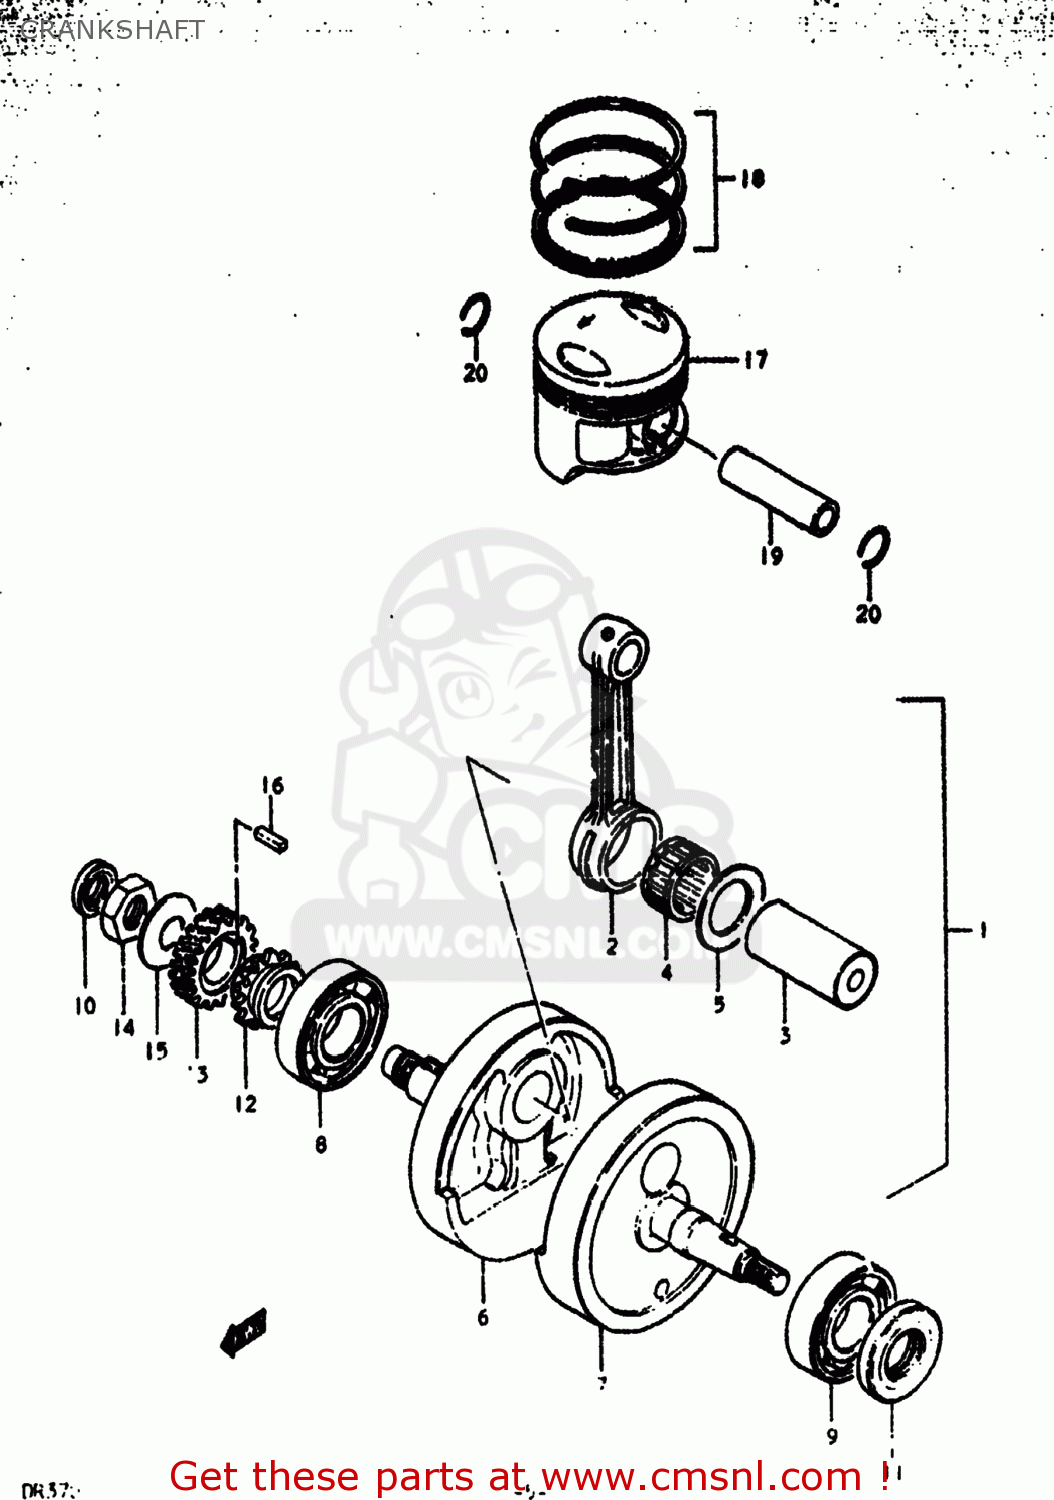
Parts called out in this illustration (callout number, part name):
1	CRANKSHAFT ASSEMBLY
2	ROD,CONNECTING
3	PIN,CRANK
4	BEARING
5	WASHER (32X50X1)
6	CRANKSHAFT
7	CRANKSHAFT,LEFT
8	BALL BEARING 30X72X19
9	BEARING
10	SEAL,OIL(16X30X6)
11	SEAL,OIL(30X58X7)
12	SPROCKET,CAM CHAIN DRIVE
13	GEAR,PRIMARY DRIVE
14	NUT (20MM)
15	WASHER
16	KEY
17	PISTON
18	RING SET,PISTON
19	PIN,PISTON
20	CIRCLIP
